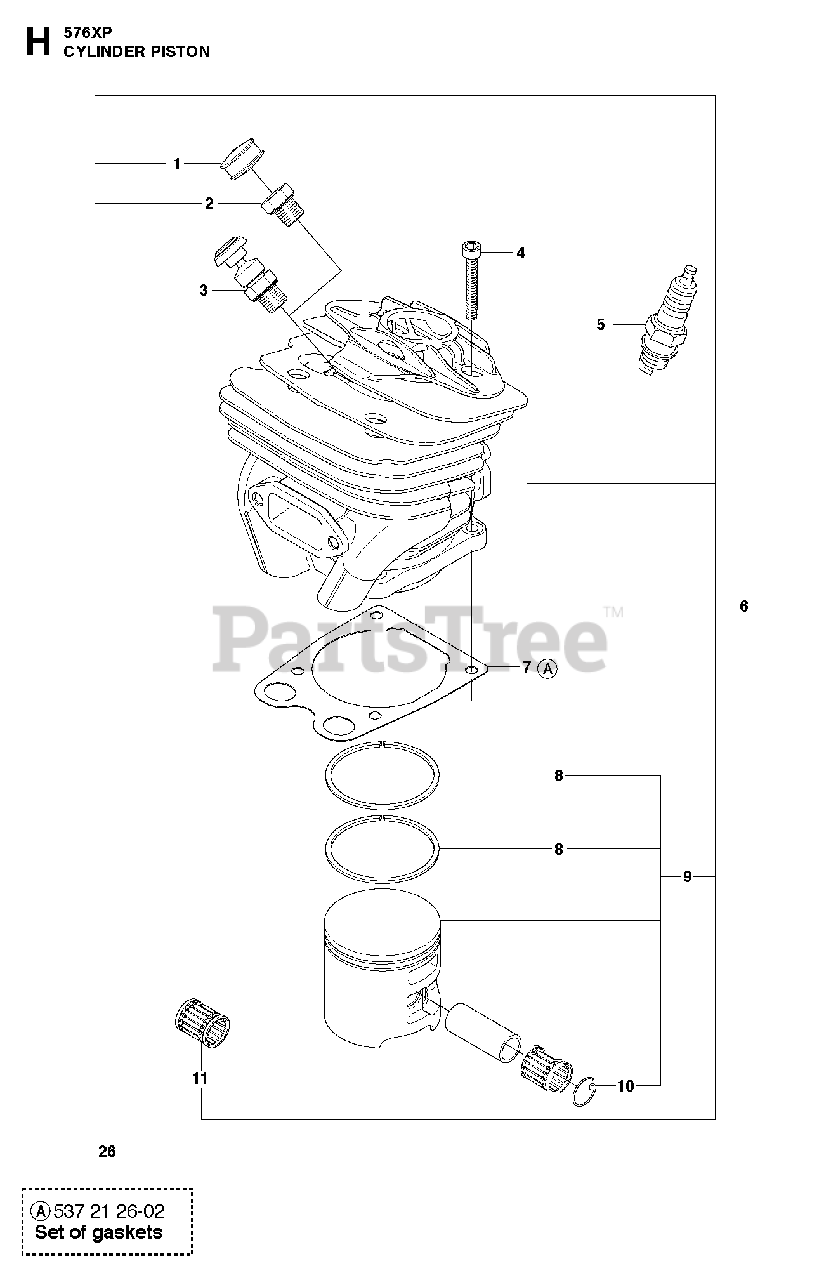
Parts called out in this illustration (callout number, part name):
1	PLUG
2	CYLINDER PLUG
3	VALVE
4	SCREW MC6S 5X25
5	BPMR7A NGK SPARK PLUG
6	CYLINDER ASSY
7	GASKET
8	%PISTON RING
9	PISTON ASSY
10	WRIST PIN CLIP
11	SUPPORT BUSHING
26	GASKET KIT
